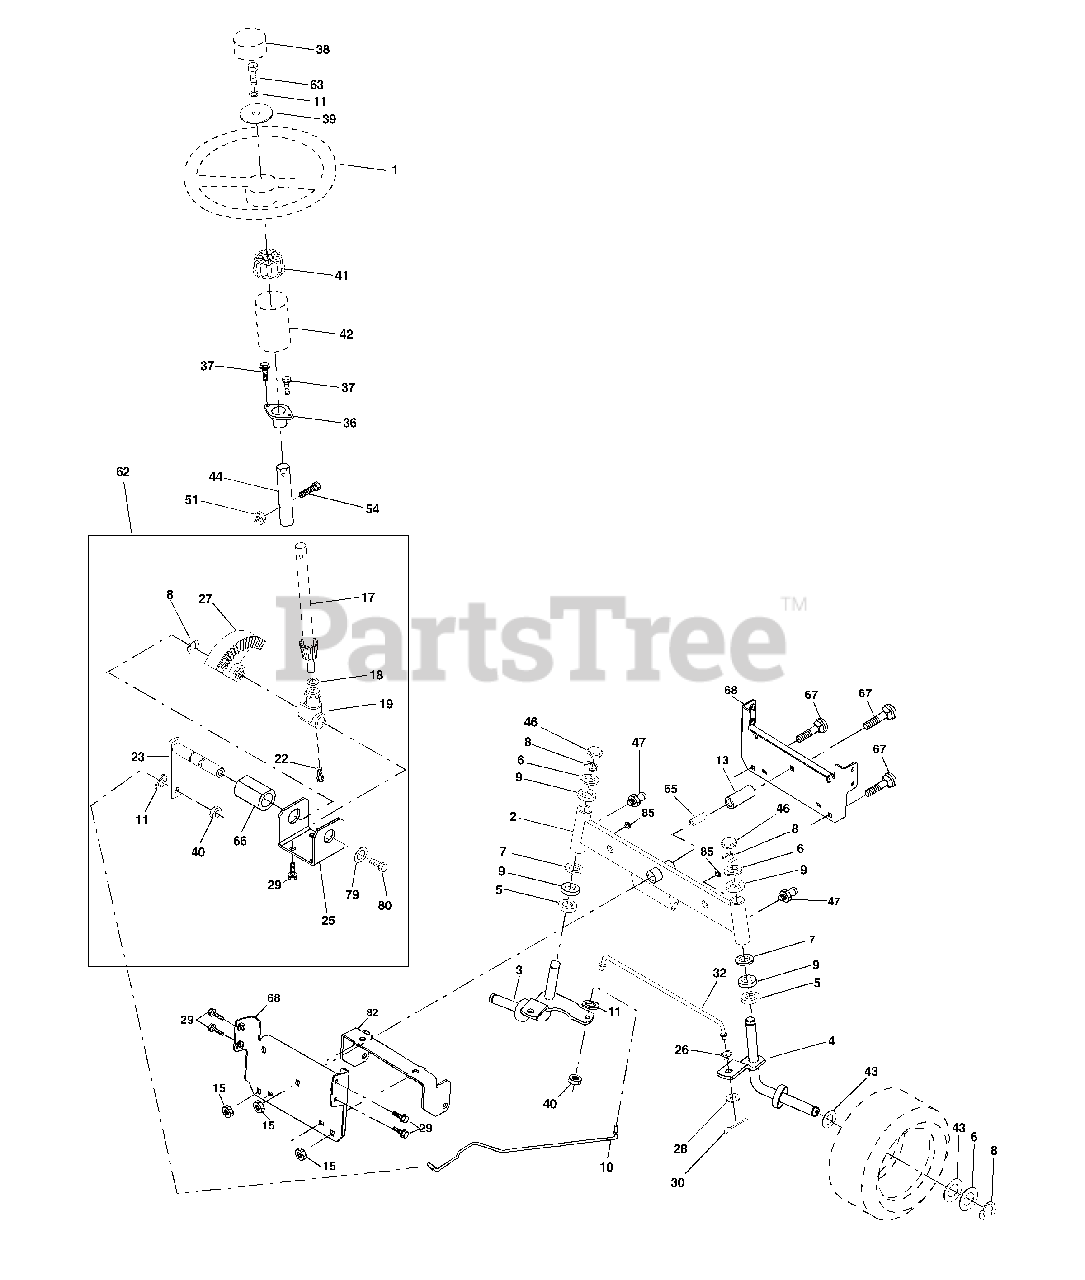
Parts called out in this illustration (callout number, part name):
1	Wheel Steering Auto Black
2	Axle Asm Front
3	Spindle Asm Lh
4	Spindle Asm Rh
5	Bearing Race Thrust Harden
6	Washer 25/32 X 1 5/8 X 16ga
7	Washer 27/32 X 1 1/4 X 16 Ga
8	Ring Klip #t5304-75
9	Bearing Col Strg Blk
10	Link Drag Extended
11	Lockwasher
13	Spacer Bearing Axle Front
15	Hex Flange Lock
17	Shaft Asm Strg 5/8 X 15 19 Lt
18	Washer Thrust 515x 750x 033
19	Support Shaft
22	Screw Hex Wsh Hd Torx
23	Shaft Asm Pittman
25	Bracket Steering
26	Bushing Rod Tie Blk Lt
27	Gear Sector
28	Washer 13/32 X 7/8 X 16ga
29	Screw 3/8-16x3/4
30	Pin
32	Rod Tie Wire Form 19 75 Mech
36	Bushing Strg 5/8 Id Dash
37	Screw TT #10-32 x 5 x 3/8 Flange
38	Insert Cap Strg
39	Washer 13/32 x 2-3/8 x 12Ga
40	Locknut Center
41	Adaptor Wheel Strg 640/ 635id
42	Boot Dash Steering
43	Washer 25/32 X 1 1/4 X 16 Ga
44	Extension Steering Non-Adjust
46	Cap Spindle Fr Top Blk
47	Fitting Grease
51	Nut Lock Hex W/Ins.
54	Bolt Fin Hex 5/16-18 Unc P
62	Kit Steering Assembly Service
63	Bolt Fin Hex 3/8-16unc x Gr. 5
65	Spacer Brace Axle
66	Bearing Arm Pittman
67	Bolt Rdhd Sq 3/8-16 Unc x 2-3/4
68	Brace Axle
79	Washer 13/32 x 1-1/4 x 12 Ga
80	Bolt Hex Nylon 3/8-16 x 3/4
82	Bracket Susp Chassis Front
85	Fastener Christmas Tree
